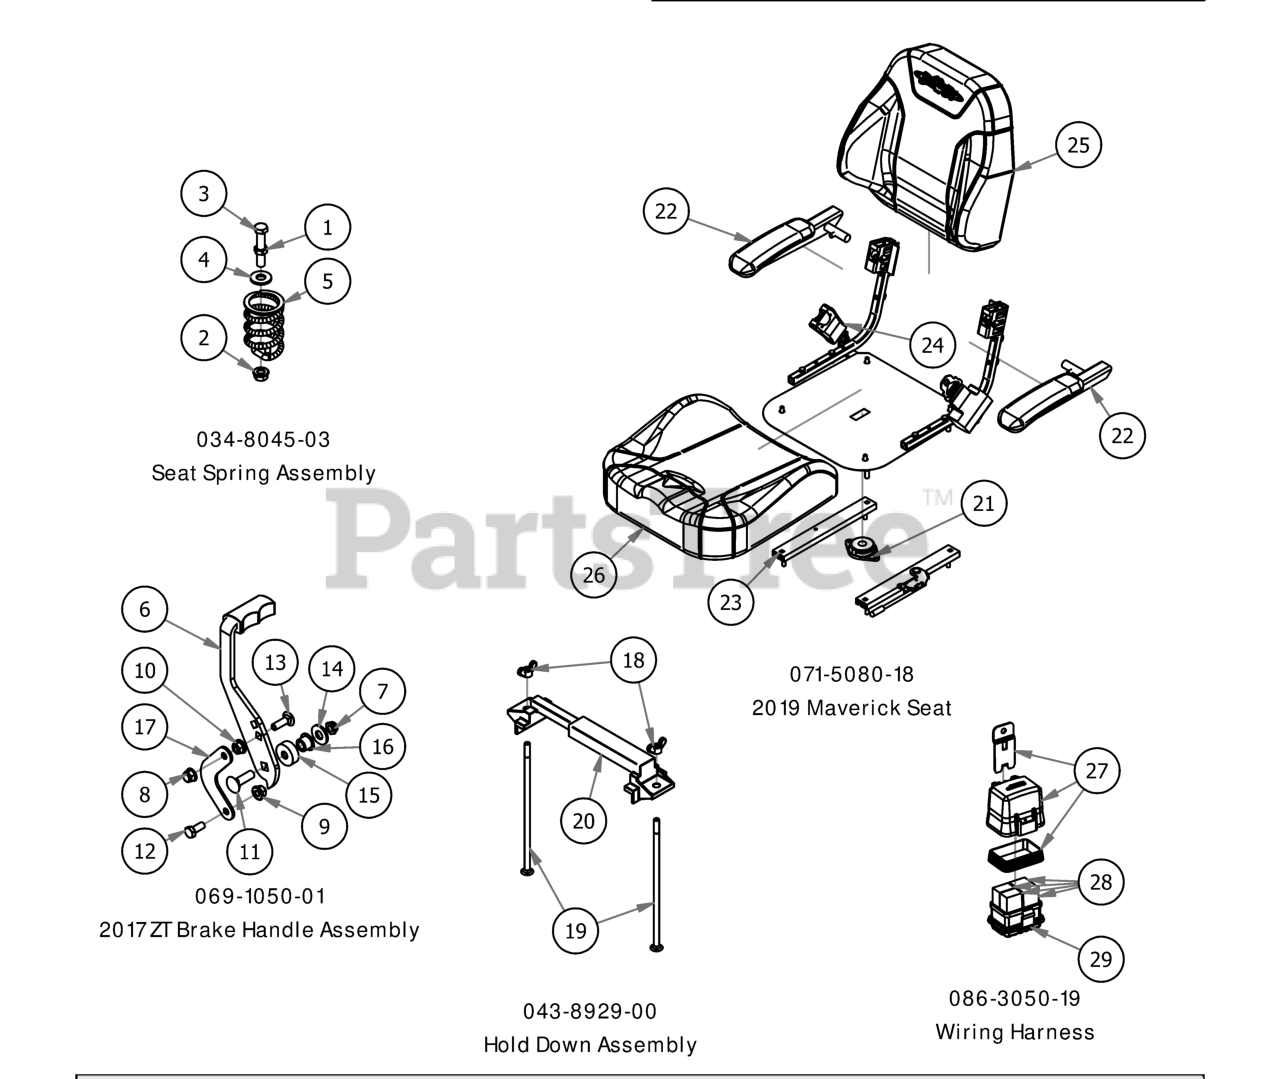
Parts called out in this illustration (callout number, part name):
1	3/8-16 Half Jam Nut
2	3/8" Flange Nut
3	3/8"-16 x 2" Gr 5 Hex Bolt
4	3/8" Flat Washer
5	Seat Spring
6	Brake Handle
7	3/8-16 Centerlock Half Nut
8	5/16-18 Nylon Insert Flange Nut (Black Cap)
9	5/16" Nylon Flange Nut
10	5/16" Flange Nut
11	3/8" x 1 1/4" Carriage Bolt
12	5/16" x 3/4" Hex Bolt
13	5/16" x 1" Carriage Bolt
14	3/8" Flat Washer
15	2015 Brake Lever Spacer
16	Bronze Bushing SF-1220-8
17	Brake Cable Adapter Bracket
18	1/4" Wing Nut
19	1/4-20 X 8 Carriage Bolt
20	Battery Hold Down
21	Seat Safety Switch
22	Seat Arm Pair
23	Seat Rails
25	Seat Back Cushion
26	Seat Cushion
27	Relay Block Cover Replacement Kit
29	Wiring Harness (Includes Cover Replacement Kit & Relays
